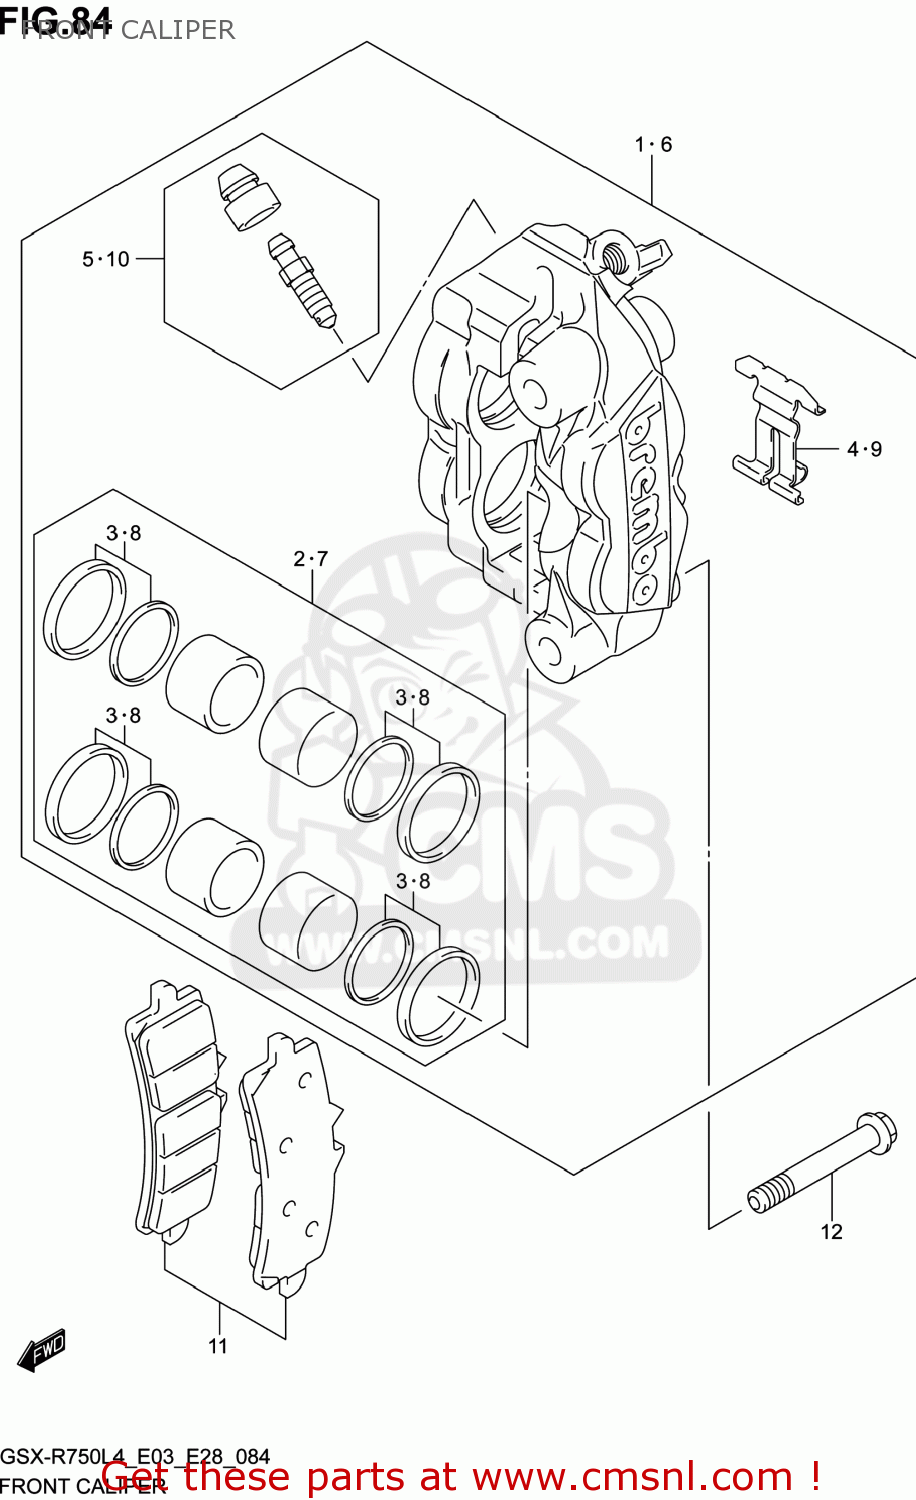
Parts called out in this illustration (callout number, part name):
1	CALIPER ASSY,FR,R
2	PISTON SET
3	SEAL SET,PISTON
4	SPRING
5	BLEEDER SET
6	CALIPER ASSY,FR,L
7	PISTON SET
8	SEAL SET,PISTON
9	SPRING
10	BLEEDER SET
11	PAD SET(T:3.5) (NAS)
12	BOLT(10X70)
